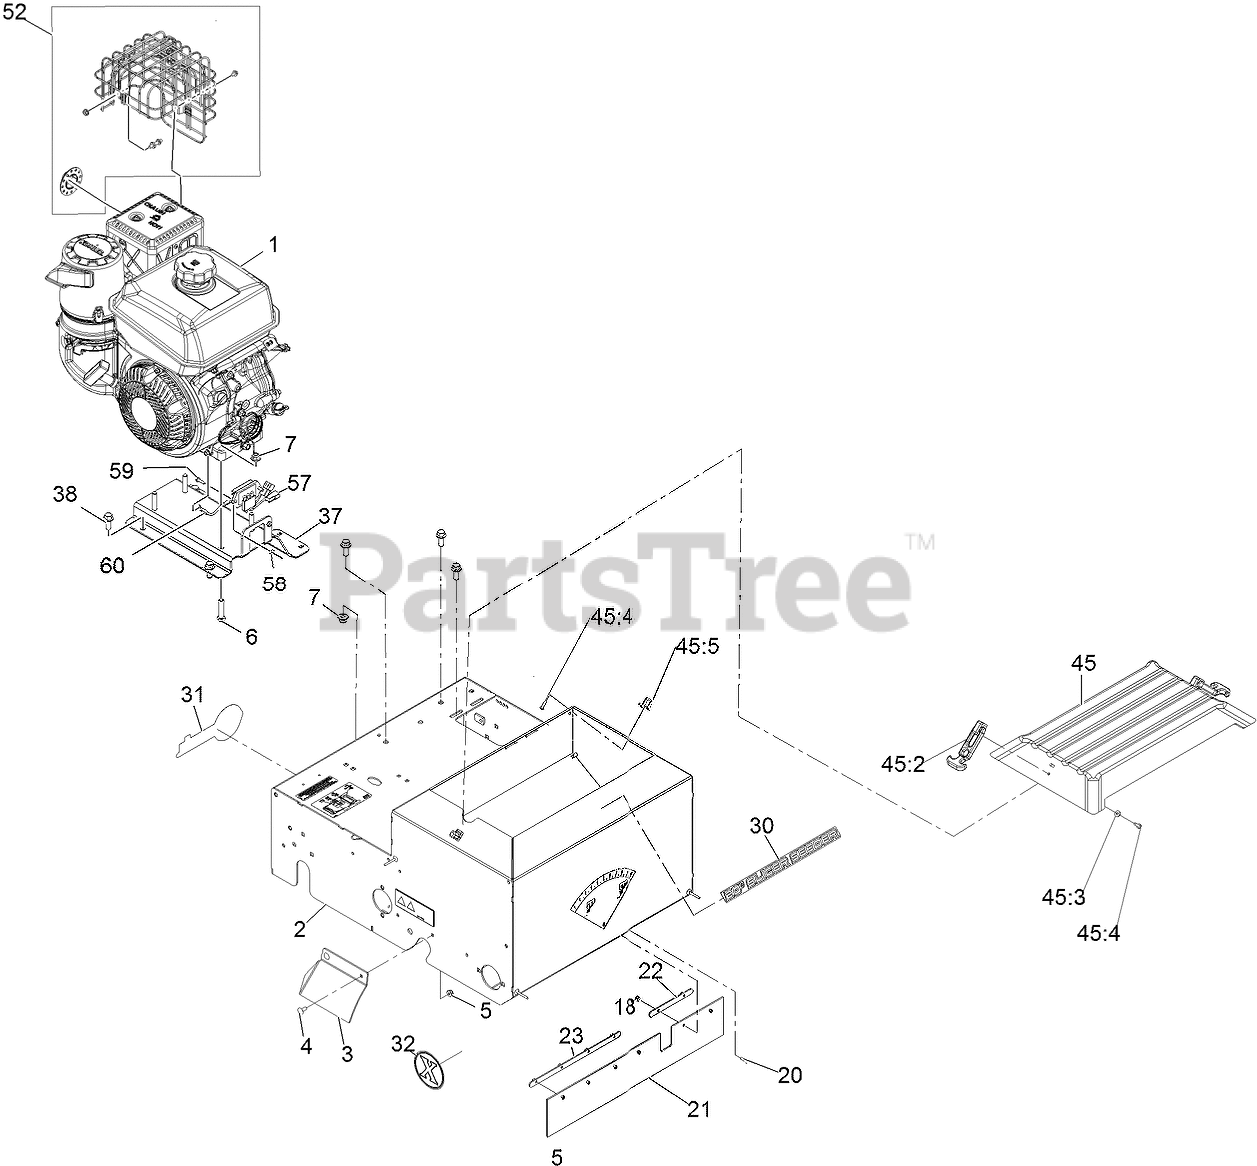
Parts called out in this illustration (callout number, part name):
2	FRAME ASM
4	SCREW-CARR
6	SCREW-HH
7	NUT-HF, NI
18	NUT-LOCK
20	SCREW-SHH
21	GUARD-DUST
22	PLATE-RETAINER
23	PLATE-RETAINER
30	Decal-Slicer Seeder Logo
31	DECAL, EXMARK LOGO
32	Decal-X-Logo
37	PLATE-ENGINE
38	SCREW-HHF 3/8-16 X 1
45	SEEDER COVER KIT
45:2	LATCH-RUBBER
45:3	WASHER-FLAT
45:4	SCREW-PPH
45:5	LATCH-KEEPER
52	Muffler Guard Kit, CH395
57	Regulator
58	KEPS Nut
59	SCREW-HWH
60	HARNESS-JUMPER, REGULATOR GROUND
